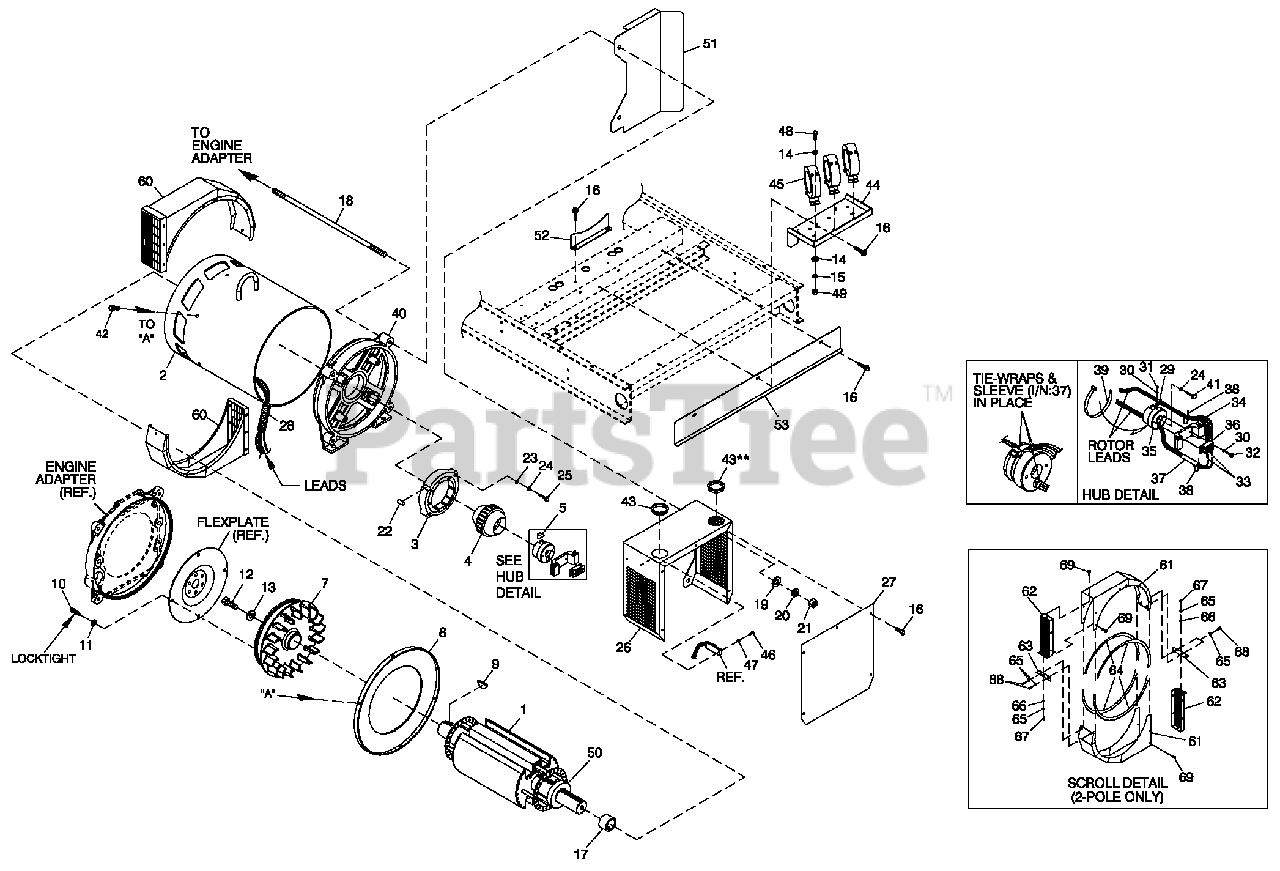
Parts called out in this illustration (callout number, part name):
1	ASSY ROTOR 2390 80KB3 CPL
2	ASSY STATOR 80KW 1PH 2P BRSHLS
3	EXITER FIELD 2" LG SPD CONN
4	ASSY EXCITER 2.0" STACK 2P
5	KEY SQ 3/8 X 3-1/4 STEEL
7	ASSY FLYWHEEL CPL
8	RING PRESSURE 390 STATOR CAN
9	KEY WOODRUFF #E
10	SCREW HHC M10-1.5X25C10.9
11	WASHER LOCK M10
12	SCREW HHC M16-2.0X45G8.8
13	SPACER .69 X 2.75 X .37 ST/ZNC
14	WASHER FLAT 1/4-M6 ZINC
15	WASHER LOCK M6-1/4
16	SCREW THF M6-1 X 16 N WA Z/JS
17	COLLAR SLIP FIT 390 MM
18	STUD M14-2.0X 760 G5 ZINC
19	WASHER FLAT M14
20	WASHER LOCK M14
21	NUT HEX M14-2.0G8YELCHR
22	PIN DOWEL 1/2 X 1-1/4
23	WASHER FLAT M12
24	WASHER LOCK M12
25	SCREW HHC M12-1.75 X 80 G10.9
26	SHIELD ALT EXCITER 390
27	COVER EXCITER SHIELD
28	CONDUIT FLEX 1.25" ID
29	CLAMP VINYL .312 X .203 Z
30	WASHER SHAKEPROOF INT #8
31	SCREW HHM #8-32X3/8
32	SCREW HHM #8-32X7/8
33	LUGRT-ANG #10/10-12
34	BRIDGE SUPPORT DIODE 15"
35	CAP END ROTOR 390MM
36	ASSY BRIDGE RECTIFIER
37	SLEEVING UL#0 .330 ID (3" LG)
38	TIE WRAP UL 3.9" X .10" BLK
39	TIE WRAP UL 17.7 X .35 BLK HT
40	REAR BEARING CARRIER CPL
41	SCREW HHC M12-1.75 X 60 G10.9
42	SCREW 1/4-20 X 5/8" TAPTITE SS
43	BUSHING SNAP SB-2.5-31
44	MOUNT CT'S 5.4L 100KW
45	TRANSFORMER
46	SCREW PHTT #6-32X1/2 ZYC
47	WASHER LOCK #6
48	SCREW HHC M6-1.0X 20 G8.8
49	NUT HEX M 6X 1.0 G8YEL CHR
50	BEARING BALL 6212 SEALED
51	SHROUD UPPER ALTERNATOR EXCITR
52	SHROUD CENTER ALTERNATR EXCITR
53	SHROUD LOWERALTERNATOR EXCITR
60	ASSY SCROLL 390 X 60MM CPL
61	SHROUD ALT SHEET METAL CPL 2P
62	SCREEN, 390 SAE ALT 60MM WIDE
63	BRACKET SAE SCROLL TENSIONER
64	VINYL TRIM 1/8" GAP
65	WASHER, SPLIT 1/4" -M6
66	WASHER FLAT 1/4ZINC
67	SCREW HHC M6-1.0 x2 5 LONG
68	SCREW HHC M6-1.0X 16 G8.8
69	SCREW SWAGE 1/4-20 X 1/2 Z/YC
